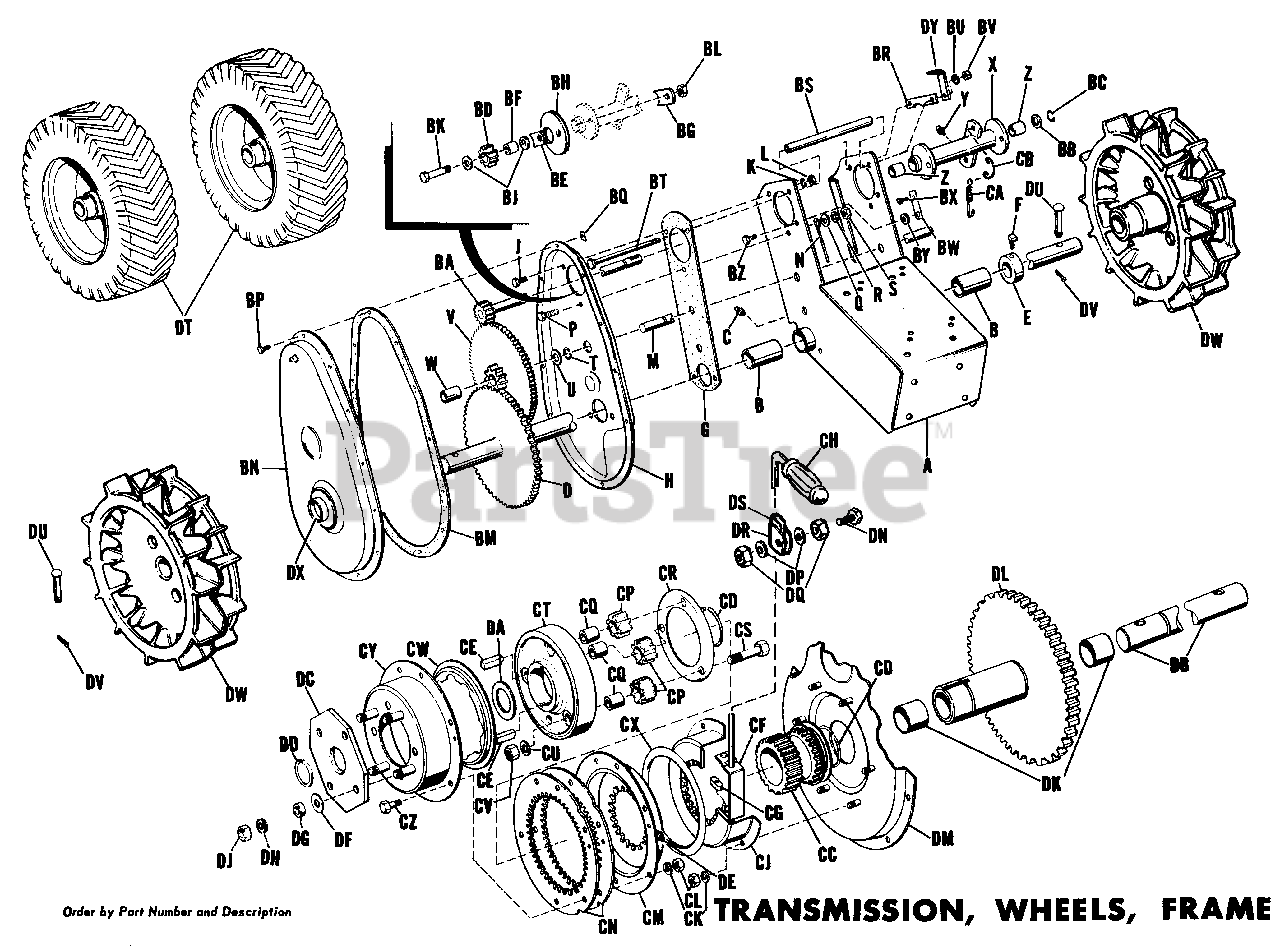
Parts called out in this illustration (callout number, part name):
A	Frame Assembly
C	Grease Fitting
D	Axle & Gear Assembly
F	Set Screw, Sq Hd, 5/16-18 x 1/2
G	Gasket, Bearing Housing
H	Gear Case
J	Hex Capscrew, 5/16-18 x 5/8
K	Lock Washer, 5/16"
L	Hex Nut, Full, 5/16"-18
M	Shaft, Intermediate
P	Hex Capscrew, 3/8"-16 x 1"
Q	Plain Washer, 3/8"
R	Lock Washer, 3/8"
S	Hex Nut, Full, 3/8"-16
T	Retaining Ring
V	Gear Assembly, Intermediate
W	Bearing, Intermediate
X	Housing Assembly, Bearing
Y	Grease Fitting
BA	Pulley Shaft Assembly
BC	Retaining Ring
BD	Reverse Pinion
BE	Reverse Pinion Spacer
BF	Pinion Spacer
BG	Lock Plate
BJ	Plain Washer, 5/16"
BK	Hex Head Bolt, L.H.
BL	Nut, Hex, Full, L.H.
BM	Gear Case Gasket
BN	Gear Case Cover Assembly
BP	Screw, Self-Tapping, #10 x 1/2"
BQ	Speed Nut
BR	Plate, Friction, Stop
BS	Spacer, Frame
BT	Bolt, Frame
BU	Washer, Lock, 5/16"
BV	Hex Nut, Full, 5/16"-18
BW	Detent, Neutral
BX	Screw, Self-Tapping, #10 x 3/8
BY	Washer, Plain, 1/4"
BZ	Hex Capscrew, 1/4"-20 x 5/8
CA	Spring, Reverse Lever
CB	Extension, Spring
DT	Wheel & Tire Assembly
DU	Pin
DV	Spring Clip
DW	Steel Wheels
DX	Seal, Felt
DY	Guide, Clutch Wire (4hp only)
